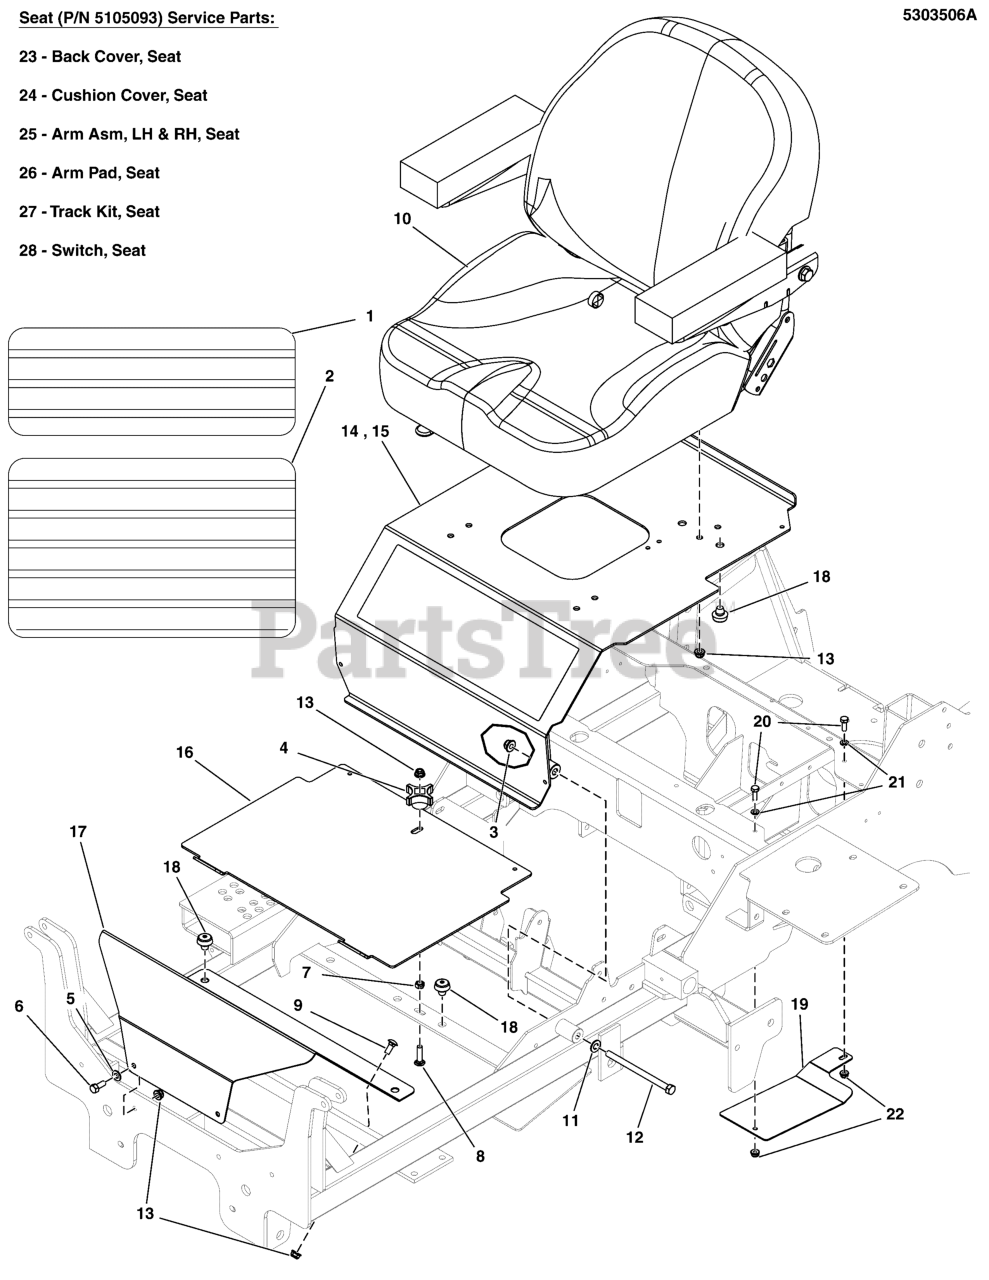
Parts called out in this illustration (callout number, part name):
1	SAFETY WALK, FLOOR REST, 16.00 X 6.00
2	SAFETY WALK, FLOOR PLATE, S50X, 10X17.13
3	NUT, 3/8 - 16 HEX NYLOCK FLANGE
4	KNOB-INT THR .312-18 4-ARM 2.12WD 1.06LG
5	WASHER, 5/16" SAE
6	BOLT, 5/16-18 X 3/4 GD5
7	NUT, 5/16-1/8, HEX, CNTR LK, ZINC PHOS/OIL
8	BOLT, 5/16-18 X 1-1/4, CARRIAGE, GD5, CZ
9	BOLT, 5/16-18 X 3/4, CARRIAGE, GD5, CZ
10	SEAT, C13, SEAT'SINC, 2016, W/SWITCH
11	WASHER, 3/8 SAE
12	BOLT, 3/8-16 X 5-1/2" GD5 CZ
13	NUT, 5/16-18 HEX NYLOCK FLANGE NUT
14	ASSM, SEAT PLATE W/ DECALS, IS2100Z (5411749B)
15	ASSM, SEAT PLATE W/ DECALS, IS2100Z EXP (5411749B)
16	PLATE, FLOOR, REMOVABLE, IS700 - RED
17	PLATE, FRONT FLOOR, IS2000Z - RED
18	MNT, VBRTN, RBBR
19	GUARD, DEBRIS, IS2100Z - BLK
20	BOLT, 1/4"-20 X 3/4" GD5 YZ
21	WASHER, 1/4 SAE
22	NUT, 1/4-20 HEX SERR. FLANGE
23	BACK, COVER, CI3 SEAT
24	CUSHION COVER, CI3 SEAT
25	LEFT AND RIGHT HAND ARM ASSEMBLIES, CI3 SEAT
26	ARM PAD, C13 SEAT
27	TRACK KIT, CI3 SEAT
28	SWITCH, SEAT
